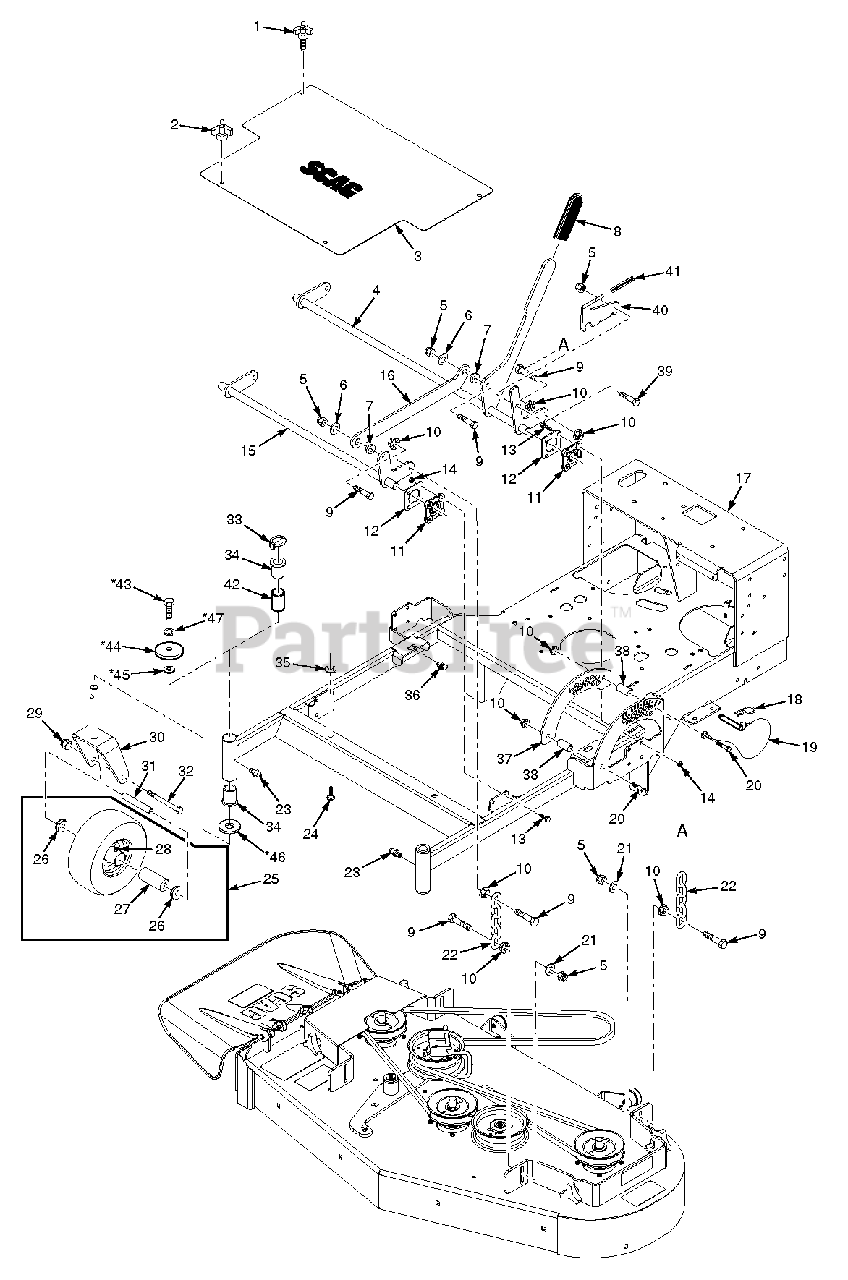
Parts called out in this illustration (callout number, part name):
1	Knob W/Stud, 3/8-16 x 1-1/4"
2	Wing Nut, 3/8" Plastic Small
3	Belt Cover w/Decals
3	Belt Cover w/Decals - SWZT61
4	Deck Bellcrank Assy.
4	Deck Bellcrank Assy. - SWZT61
5	Nut, Elastic Stop 3/8-16
6	Flatwasher, 3/8-.391 x .938 x .105
7	Bushing
8	Grip, Deck Lift
9	Bolt, Hex Head 3/8-16 x 1-1/2"
10	Nut, Serrated Flange 3/8-16
11	Bearing, Deck Lift
12	Reinforcement, Bearing
13	Cpscrw, 5/16-18 x 1"Serrated Flange Hex Head
14	Nut, Center Lock 5/16-18
15	Deck Lift Weldment, Front
15	Deck Lift Weldment, Front - SWZT61
16	Link, Decklift
16	Link, Decklift -SWZT61
17	Frame w/Decals (SWZT 36 & 48)
17	Frame w/Decals (SWZT 52)
17	Frame w/Decals (SWZT 61)
18	Hair Pin Cotter
19	Pin Assembly w/Lanyard
20	Bolt, Hex Head 3/8-16 x 2-1/2"
21	Flatwasher, 3/8-.391 x .938 x .105
22	Chain
23	Grease Fitting
24	Bolt, Carriage 3/8-16 x 1"
25	Flat-Free Tire Assy.
25	Flat-Free Tire Assy. - SWZT61
26	Retainer, Caster Wheel Bearing
27	Roller Bearing, Caster Wheel
28	Grease Fitting, 45 Degree 1/4-28
29	Nut, Elastic Stop 1/2-13
30	Caster Yoke
30	Caster Yoke - SWZT61
31	Sleeve, Caster Wheel Bearing
31	Sleeve, Caster Wheel Bearing - SWZT61
32	Bolt, Hex Head 1/2-13 x 5-1/2"
33	Quick Pin
34	Bronze Bearing
35	Nut, Push-On 3/8"
36	U-Nut 3/8-16
37	Bracket, Deck Height
38	Spacer
39	Bolt, Hex Head 3/8-16 x 1"
40	Lever Assembly, Deck Latch
41	Grip, Deck Transport Lock
42	Spacer, Caster Bearing
43	Bolt, Hex Head 3/8-16 x 1"
44	Flatwasher, 3/8-.406 x 2.25 x .188
45	Flatwasher, 7/16-.500 x 1.250 x .083
46	Spacer, Yoke
47	Lockwasher, 3/8" Spring
